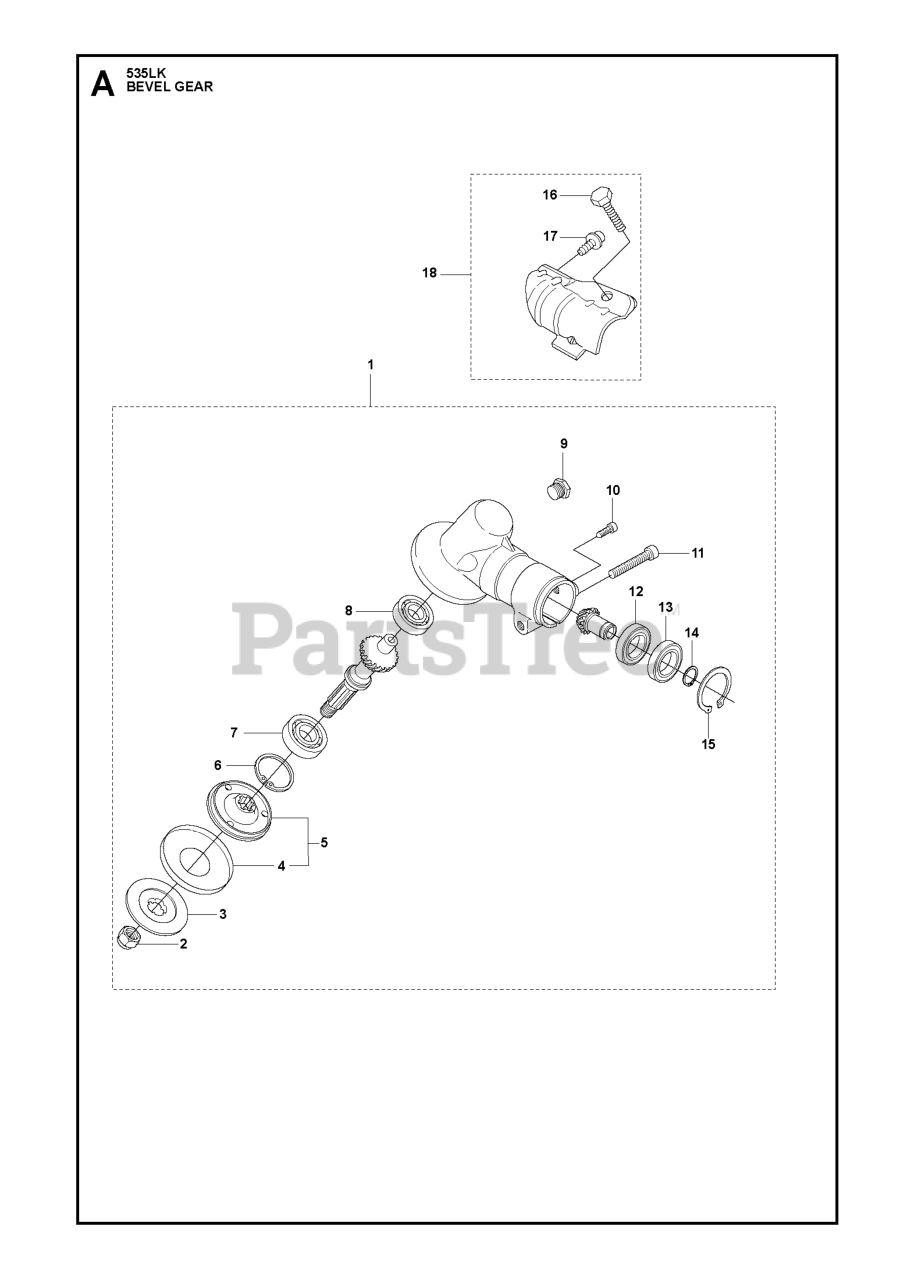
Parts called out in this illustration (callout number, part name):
1	GEAR HEAD
2	GEARHEAD NUT - BRUSHCUTTER
3	SUPPORT FLANGE
4	WASHER
5	DRIVE DISC
6	RETAINING RING SGH 28
7	BEARING
8	BALL BEARING 8X22X7/608Z
12	BALL BEARING 24X9X1/609ZR
14	RETAINING RING
15	RETAINING RING
16	SCREW M6S 6X20
18	RP BRACKET TRIMMER GUARD
